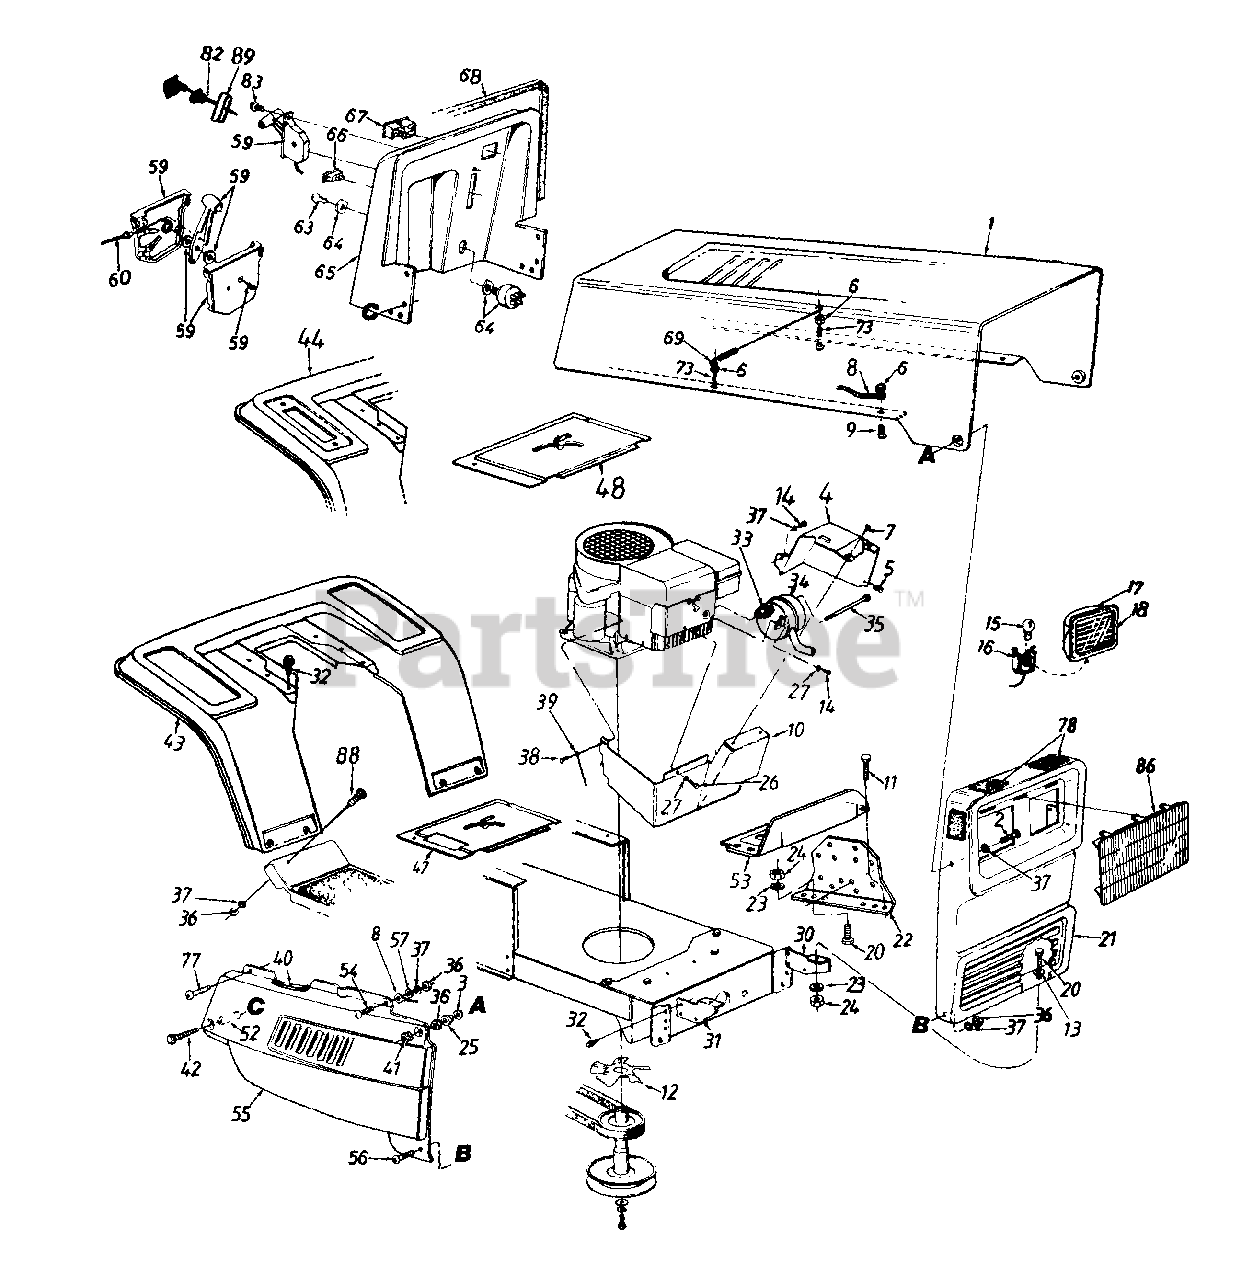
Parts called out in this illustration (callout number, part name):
1	Hood
2	Hex Bolt 1/4-20 x .88" Lg.
3	Washer .39" I.D. x .62"
4	Muffler Heat Shield - L.H.
5	Speed Nut #10-24 Thd.
6	Hex Sems Nut #10-24 Thd.
7	Hex B-Tap Scr. #10 x .38" Lg.
8	Hood Stop
9	Truss Hd. Scr. #10-24 x 1/2"
10	Muffler Heat Shield - Front
11	Hex Wash. Hd. B-Tap Scr. 5/16-18 x .5" Lg.
13	Fl-Wash. .344" I.D. x 1" O.D.
14	Hex Tap Scr. 1/4-20 x .5" Lg.
15	Bulb
16	Twist Lock - Bulb Socket
17	Headlight Housing
18	Lens
20	Hex Bolt 5/16-18 x .75" Lg.
24	Hex Nut 5/16-18 Thd.
25	Shld. Spacer
26	Hex Bolt 1/4-20 x 3/8" Lg.
27	Spr. Wash. 1/4" I.D.
30	Grille Mount Brkt.- L.H.
33	Exhaust Gasket
34	Muffler (B&S)
35	Shoulder Bolt
36	Hex Nut 1/4-20 Thd.
37	L-Wash. 1/4" I.D.
38	Truss Mach. Scr. 5/16-18 x .75" Lg.
39	Ground Wire 7.5"
40	Trim Strip - 12"
41	Acorn Nut 1/4-20 Thd.
42	Hex TT-Tap Scr. 1/4-20 x 1.75" Lg.
52	Spacer 1.32" Lg.
57	Fl-Wash..281" I.D. x .73" O.D.
59	Throttle Control Box Ass'y.
60	Throttle Control Wire (B&S)
63	Ignition Key
64	Ignition Switch
67	Ammeter
68	Trim Strip - 31"
69	Hood Spring
73	Hex Scr. #10-24 x 1.0" Lg.
77	Hex Wash. Hd. Tap Scr. 1/4 x .75" Lg.
78	Foam Strip 3/8 x 1-1/8" x 1-1/2 Lg.
82	Choke Control 29" Lg.
83	Truss Mach. AB-Tap Scr. #10 x .5" Lg.
86	Headlight Bezel
88	Truss Mach. Scr. 1/4-20 x .5" Lg.
89	Retainer Clip
